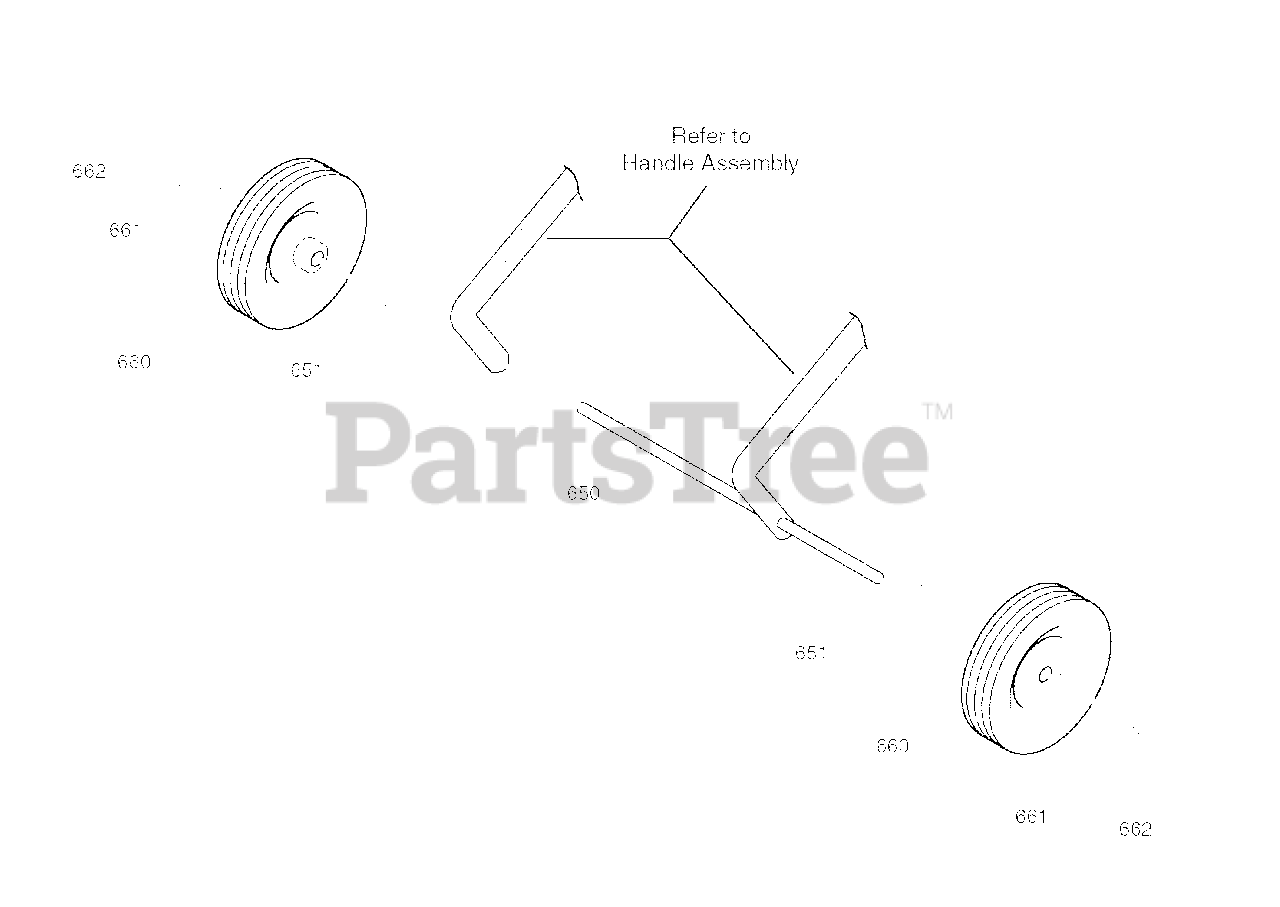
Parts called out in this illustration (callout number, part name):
650	AXLE, 20.53 WHEEL 20/21
651	WASHER, FLAT .391 X 1.00 X .125
660	TIRE & RIM 7 X 1.50
661	WASHER, FLAT .391 X 1.00 X .125
662	RING, RETAINER E
